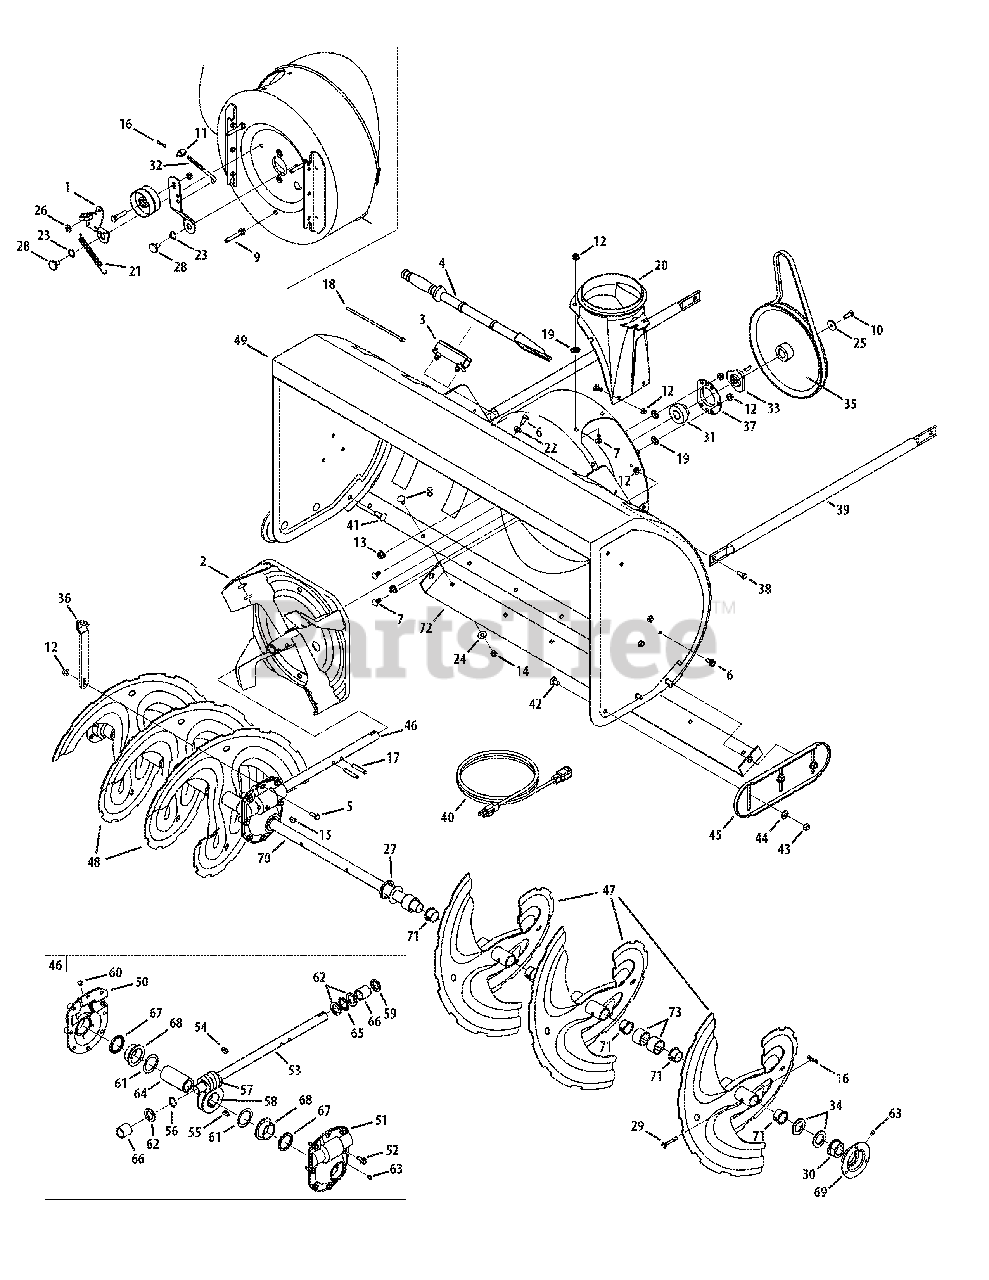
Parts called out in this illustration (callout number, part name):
1	Bracket Assembly, Auger Brake
3	Clip, Mounting
4	Tool, Clean-out
5	Screw, Hex Cap, 5/16-18 x 1.0 Gr5
6	Screw, 5/16-18 x .750
7	Screw, Carriage, 5/16-18 x .75
8	Screw, Carriage, 5/16-18 x .75 Stainless
9	Screw w/Stud, 5/16-18 x .4300
10	Screw, Hex Cap Lock, 5/16-24 x .875
11	Ferrule
12	Nut, Hex Flange Lock, 5/16-18
13	Nut, Hex Flange Lock, 3/8-16
14	Nut, Hex, 5/16-18 Stainless
15	Key, Woodru, 1/4 x 3/4
16	Pin, Bow-tie Cotter
17	Pin, Spiral, 5/16 x 1.75
18	Cable Tie
20	Adapter, Chute, 6"
21	Spring, Extension
22	Washer, Flat, .349 x .879 .063
23	Washer, Wave, .625 x .885 x .015
24	Washer, Bell., .34 x .872 x .06 Stainless
25	Washer, Flat, .34 x 1.5 x .15 Ht.
26	Washer, .344 x .75 x .12
27	Washer, 1.01 x 1.86 x .06
28	Screw, Shoulder, .625 x .17
29	Pin, Shear, .25 x 1.75
30	Bearing, Flange w/Flats
31	Bearing, Self Aligning
32	Rod, Auger Idler
33	Adapter, Pulley w/Pins
34	Spacer, 1.004 x 1.375 x .25
35	Pulley, Auger Drive, 10.0
37	Housing, Bearing
38	Screw, 5/16-18 x .75 GR5
41	Screw, Carr,3/8-16 x 1.0 Stainless
42	Screw, Carriage, 3/8-16 x .75 Stainless
43	Nut, Hex Lock, 3/8-16 Stainless
44	Washer, Bell., .375 x .87 x .063 Stainless
46	Gear Box Assembly
50	Housing Assembly, Auger, RH
51	Housing Assembly, Auger, LH
52	Screw, LD, 5/16-18 x .750
53	Auger Drive Shaft
54	Key, Hi Pro, 3/16 x 3/4
55	Key, 1/4 x 3/4 Dia.
56	External Retainer Ring
57	Gear, Worm
58	Gear, Worm, LH
59	Seal, Oil
61	Wash, Flat, 1.52ID x 2.0 OD
62	Wash, Flat, .88 ID x .38 OD
63	Grease Fitting, 3/16
64	Worm Gear Shaft
65	Bearing, Thrust
66	Sleeve
67	Oil Seal
68	Flange Bearing
70	Axle, Spiral
71	Flange Bushing
72	Shave Plate
73	Spacer, 1.50 x 1.00 x 1.00
